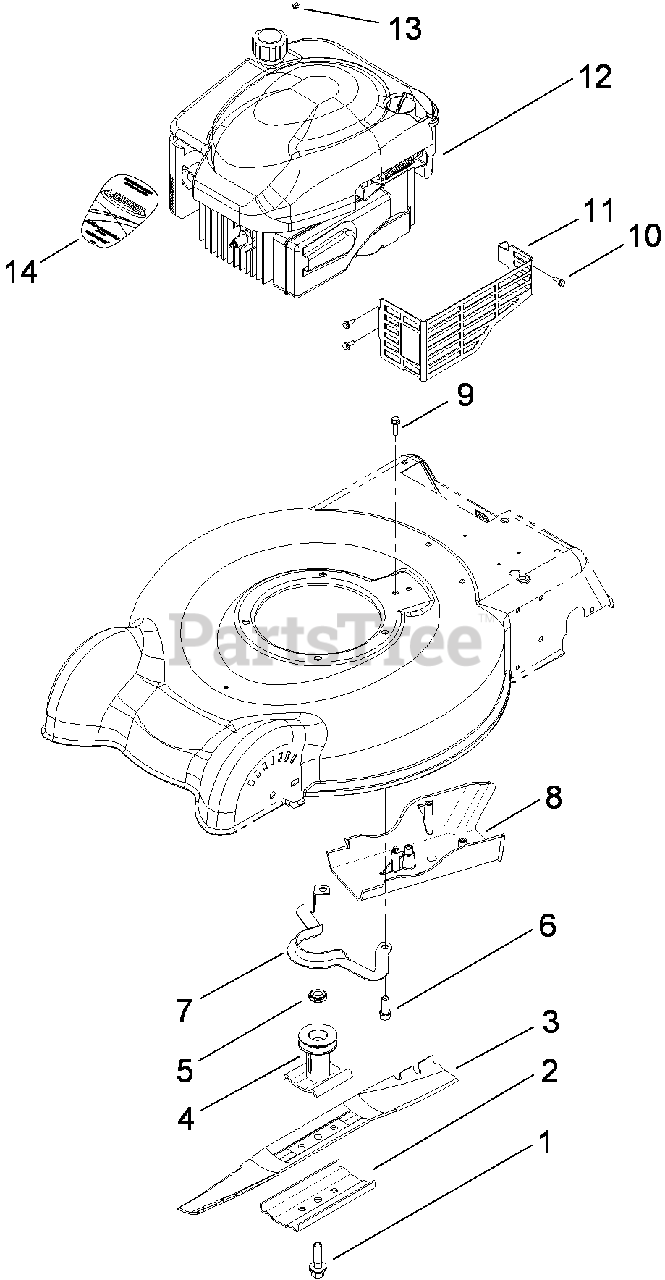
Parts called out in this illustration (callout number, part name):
1	BOLT-BLADE
2	SUPPORT-BLADE
3	BLADE-20 INCH
4	BLADE DRIVER ASM
5	Spacer-Driver
6	SCREW-TAPTITE
8	COVER-BELT
9	SCREW-HWH
10	SCREW-TAPTITE
11	SHIELD-MUFFLER
13	STOP-ROPE
